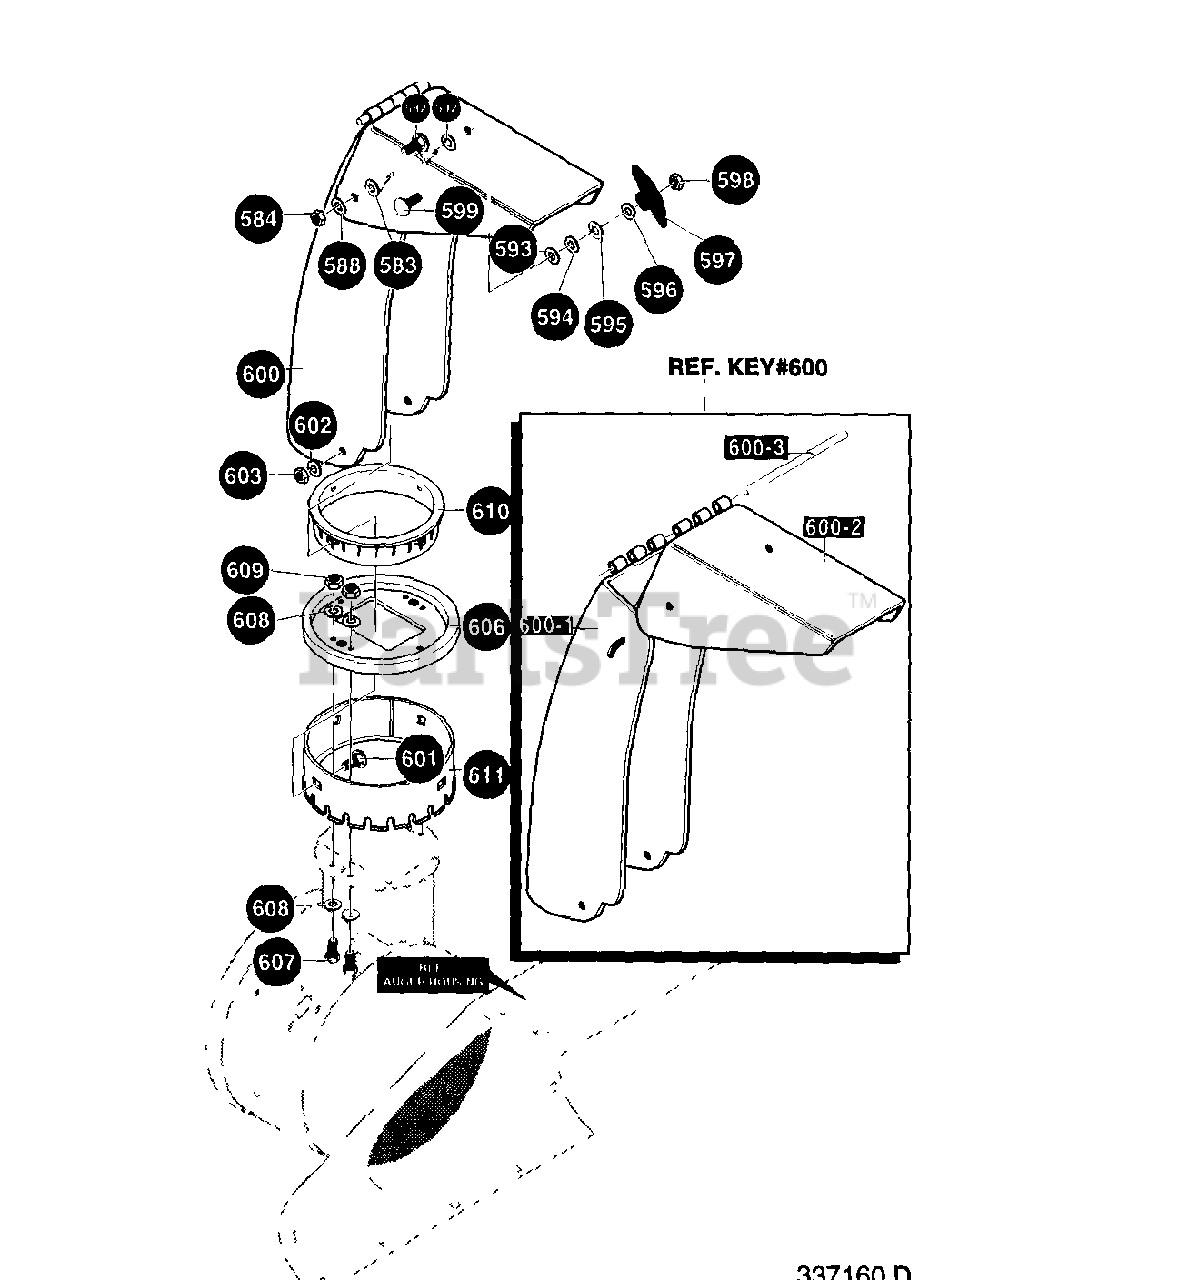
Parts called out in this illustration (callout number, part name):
582	Bolt, 5/16-18 x .75
583	Washer, Pl .438 x .75 x .064
584	Nut, 5/16-18 Reghexctrlk
588	Washer, 315 x .75 x .064
592	Washer, Pl 438 x .75 x .064
593	Washer, 315 x .75 x .064
594	Flatwasher 344 x .69 x .065
595	Washer, .328 x .60 x .09
596	Flatwasher 344 x .69 x .065
597	Knob, T
598	Nut, 5/16-18 Reghex
599	Bolt, Carr 5/16-18 x 1.00
600	Chute Assembly
601	Bolt, 5/16-18 x 1.00
602	Flatwasher, .344 x .69 x .065
603	Nut,5/16-18 Hexnyl
606	Collar, Chute
607	Screw, 1/4-20 x .75
608	Flatwasher, 281 x .63 x .065
609	Nut, 1/4-20
610	Retainer, Ring Inner
611	Retainer, Ring Outer
6001	Lower Chute
6002	Upper Chute
